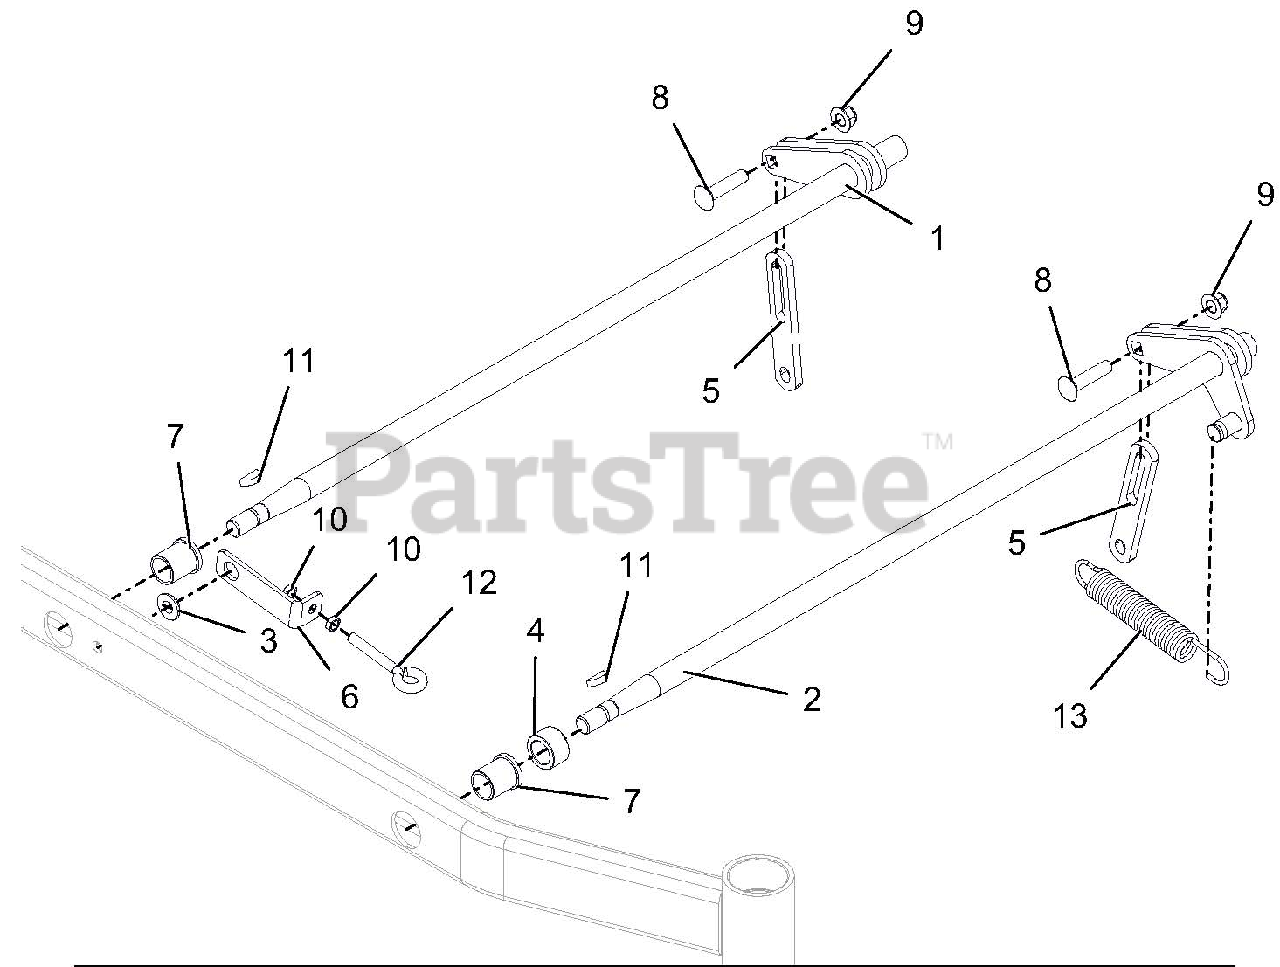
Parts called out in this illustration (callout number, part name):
1	REAR LH DECK LIFT ARM WLDMT-LF
2	FRT LH DECK LIFT ARM WLDMT-LF
3	BSHG-FLG .515X.750X.310X1.120
4	SPACER, 1.500 X 1.000 X .880
5	LINK-DECK LIFT - LONG
6	SPRING ANCHOR BRACKET - RED
7	BSHG-FLG 1.00X1.25X1.50X1.50
8	BLT-RDHDSQNK .50-13X2.25 G5YZ
9	@NUT-LK-NYL-FLG .50-13 YWZC
10	NUT-HEX-JAM .375-16 YWZC
11	KEY-WDRF .25X1.00 HRD #15
12	BLT-EYE .375-16X2.50 YWZC
13	SG-TENS .162X1.25X8.25 WLD 25
